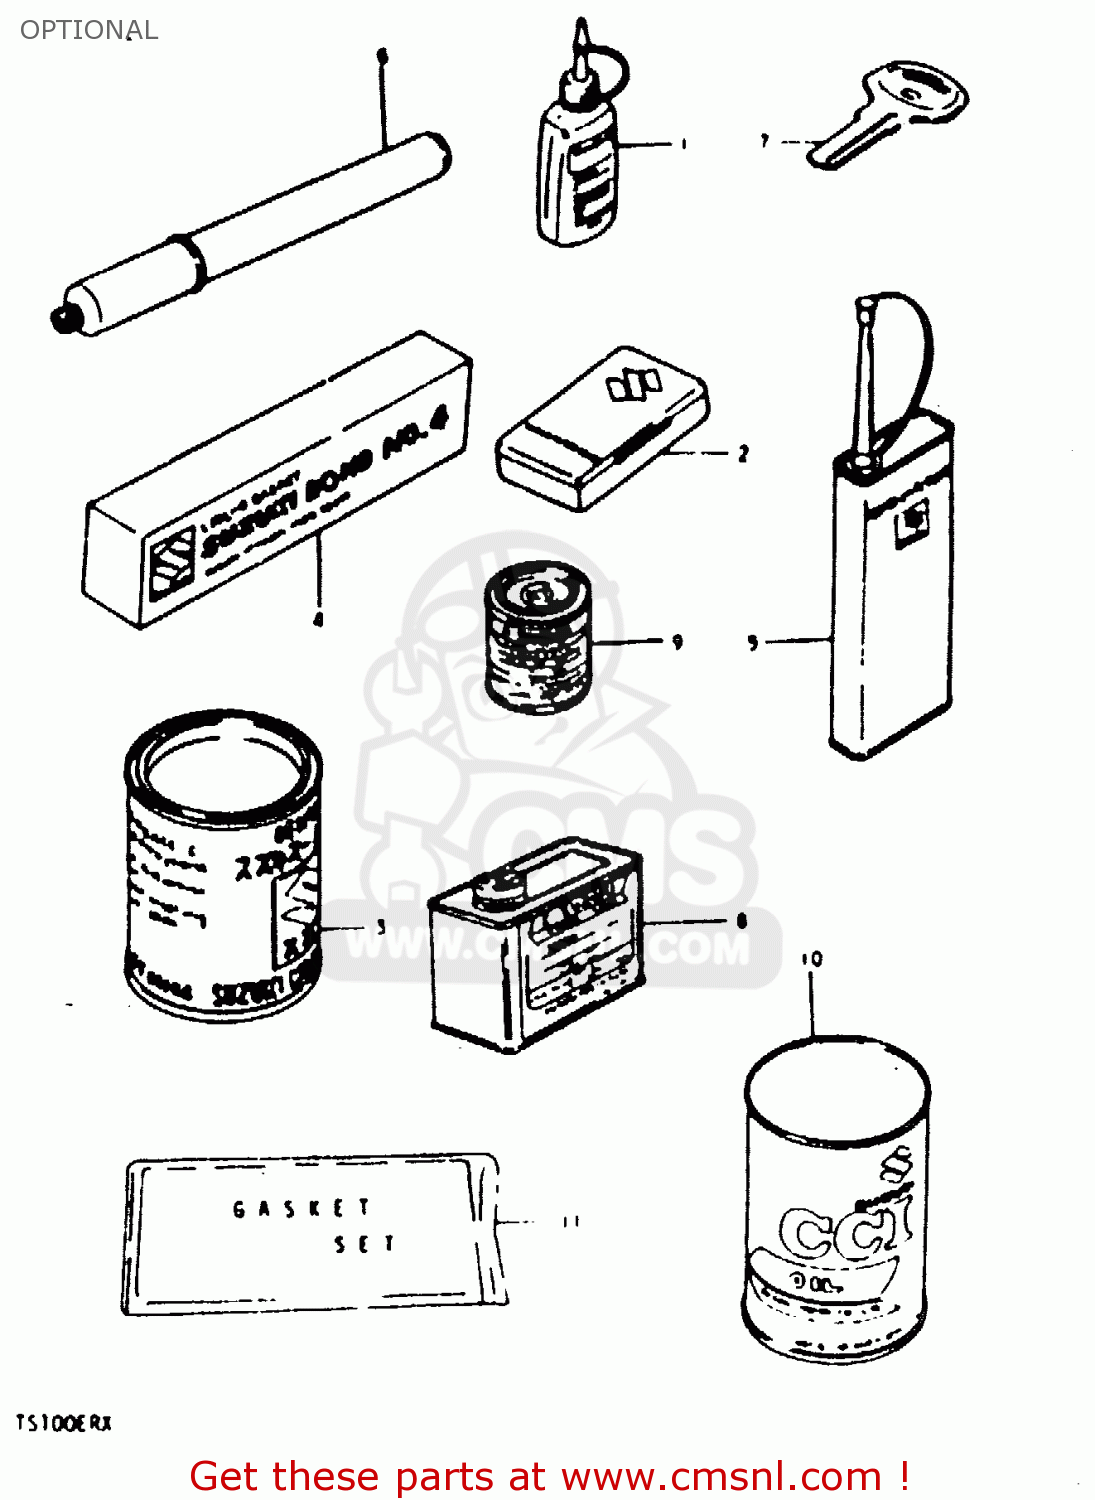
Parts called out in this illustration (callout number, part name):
1	THREAD LOCK NO.1303B PURPL 50G
2	TUBE REPARING TOOL
3	GREASE(C)EP2 LITHIUM 150G
4	BOND 1104
5	THREAD LOCK NO.1401 CLEAR 200G
6	INFLATOR, AIR
7	KEY,BLANK
8	PAINT (BLACK)
9	PAINT,BLACK
10	CCI OIL
11	GASKET SET (MCA)
